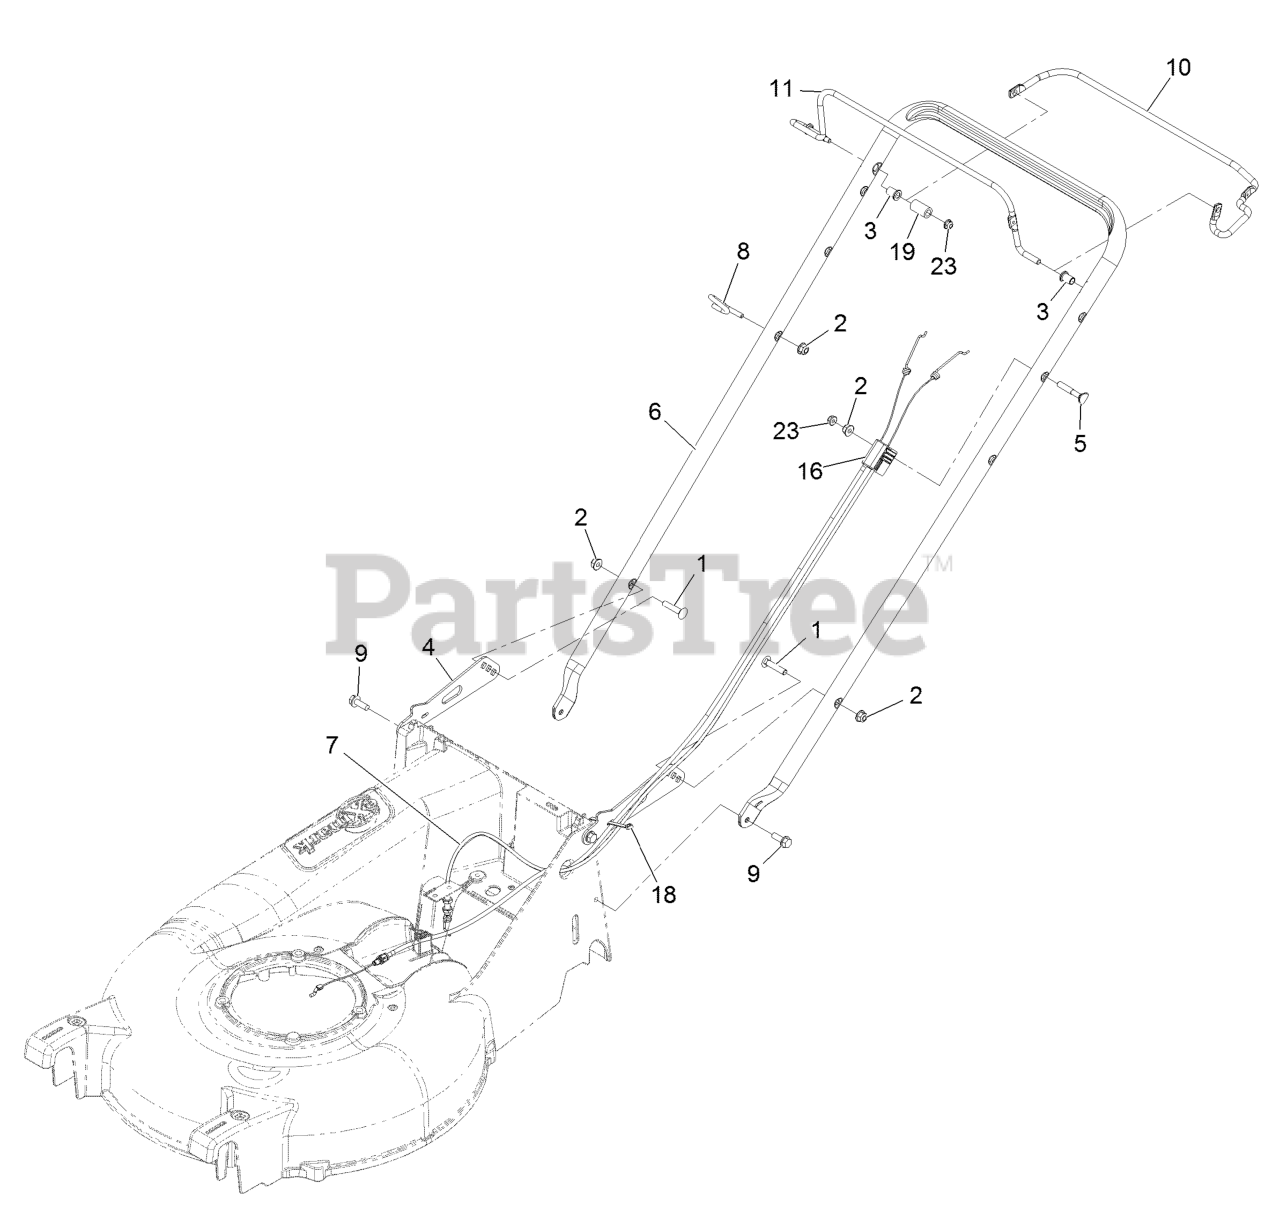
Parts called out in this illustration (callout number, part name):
1	BOLT-CARR
2	NUT-HF, NI
3	BUSHING-HANDLEBAR
4	BRACKET,HANDLEBAR
6	HANDLEBAR-P21
8	GUIDE,ROPE
9	SCREW-TAPTITE
10	BAIL-DRIVE COATED
16	CABLE-ZONE KAWASAKI
18	TIE-CABLE
